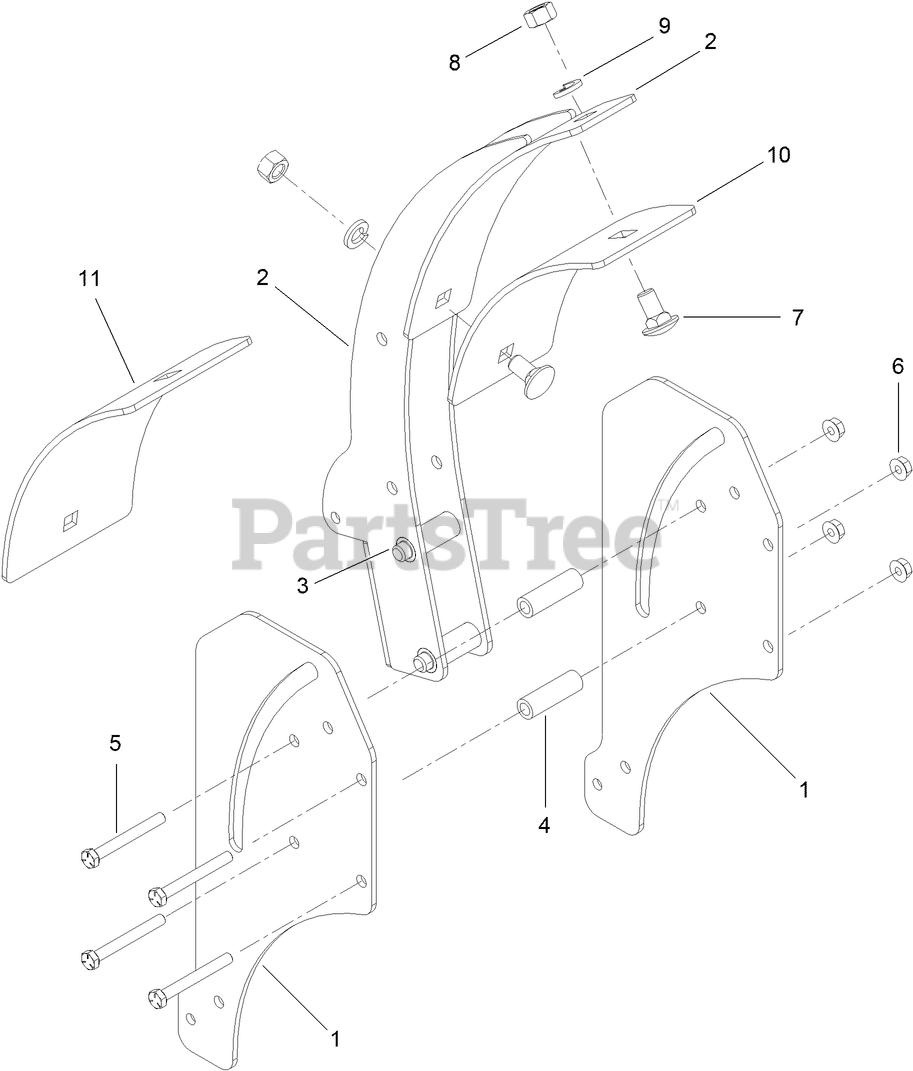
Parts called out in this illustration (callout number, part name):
1	CRUMBER SLIDE
2	PEDESTRIAN CRUMBER BASE
3	CRUMBER PIN
4	CRUMBER SPACER
5	SCREW-HH
6	NUT-HF
7	SCREW-CARR
8	NUT-HH
9	WASHER-LOCK
10	CRUMBER DRAG - 4"
11	CRUMBER DRAG - 6"
